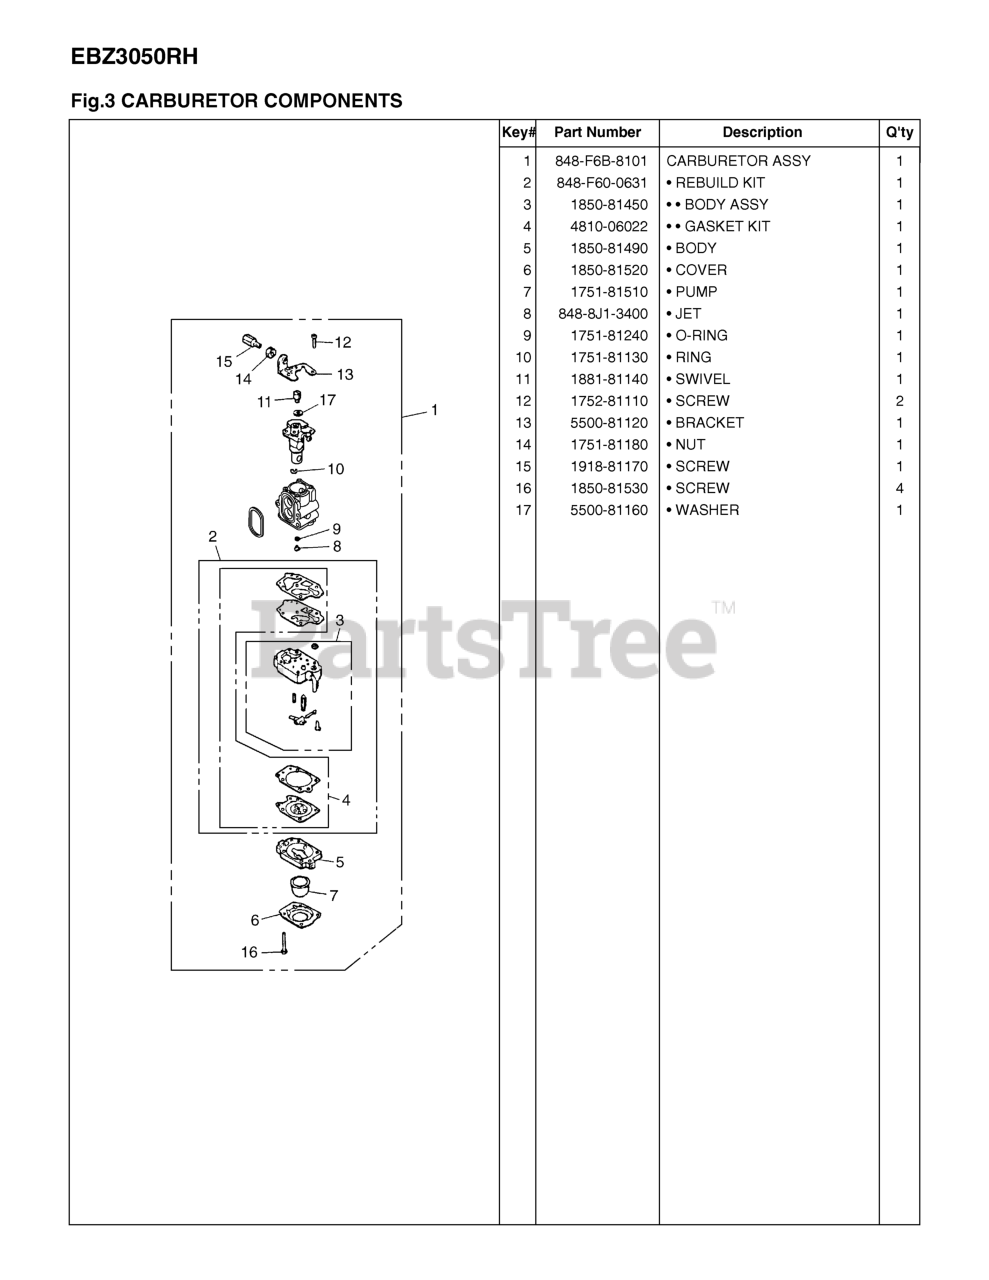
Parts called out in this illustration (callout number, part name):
1	CARBURETOR ASSY
2	REBUILD KIT
3	BODY, PUMP
4	GASKET KIT
5	BODY, PURGE
6	COVER, PUMP
7	PUMP, PRIMING
9	RING, O
10	RING
11	SWIVEL
12	SCREW
14	NUT, CABLE ADJUSTER
15	SCREW, CABLE ADJUSTER
16	SCREW
17	WASHER
